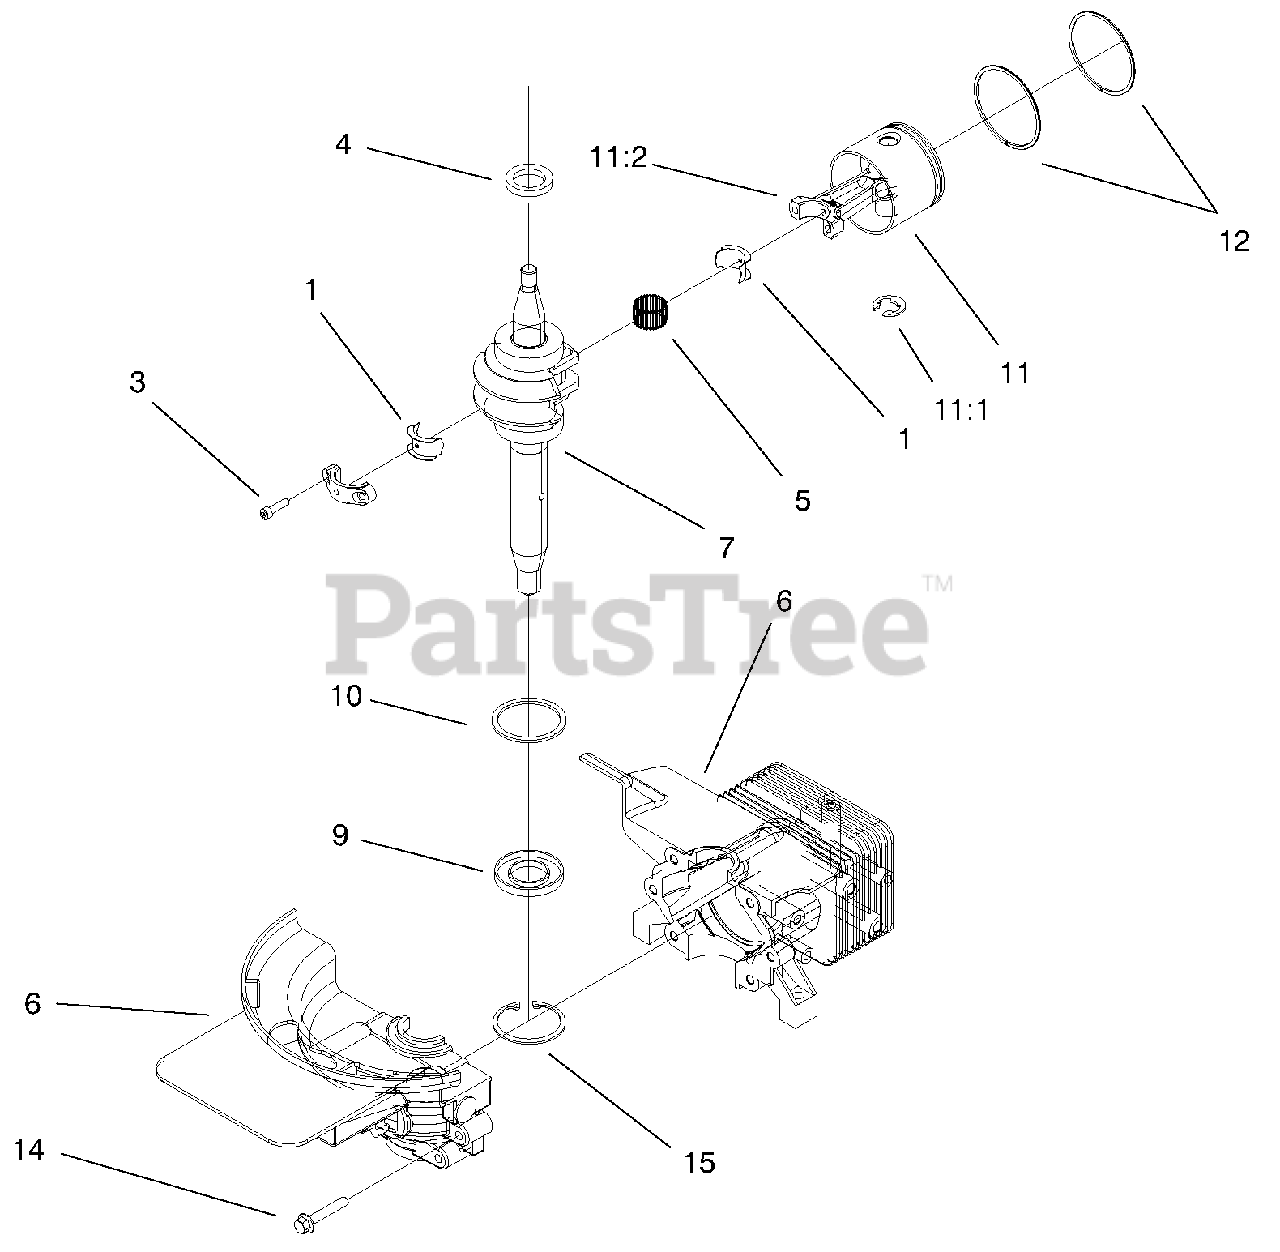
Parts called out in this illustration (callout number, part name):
1	Liner ASM
4	Oil Seal
5	Needle Bearing
6	Cylinder & Ccase ASM w/S
7	Crankshaft & Bearing ASM
9	Oil Seal
10	Ring Retaining
11	Piston & Rod ASM
11:1	Ring-Retaining
11:2	Connecting Rod
12	Ring Set
14	Screw-HWH
15	Ring-Retaining
